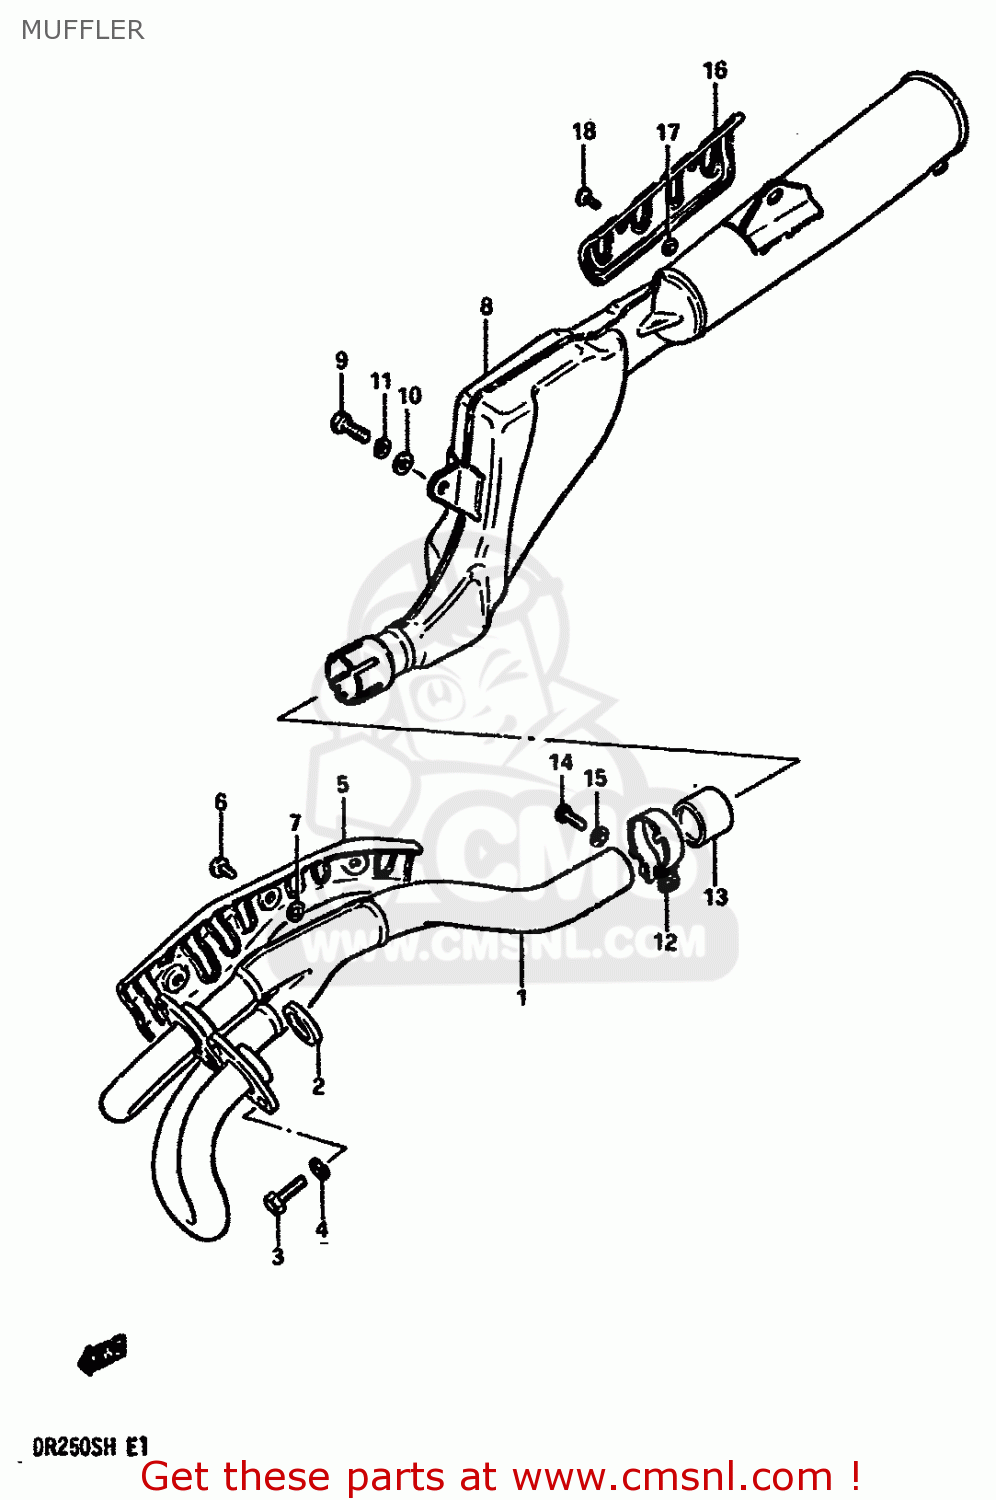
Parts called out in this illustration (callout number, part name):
1	PIPE,EXHAUST
2	GASKET,EXHAUST PIPE (NAS)
3	BOLT
4	WASHER,LOCK
5	COVER,EXHAUST PIPE
6	SCREW
7	GASKET 6.2X12X1.5 (MCA)
8	MUFFLER ASSY
9	BOLT
10	WASHER
11	WASHER,LOCK,8.
12	CLAMP
13	CONNECTOR,MUFFLER
14	BOLT 8X35
15	WASHER
16	COVER,MUFFLER
17	GASKET 6.2X12X1.5 (MCA)
18	SCREW
